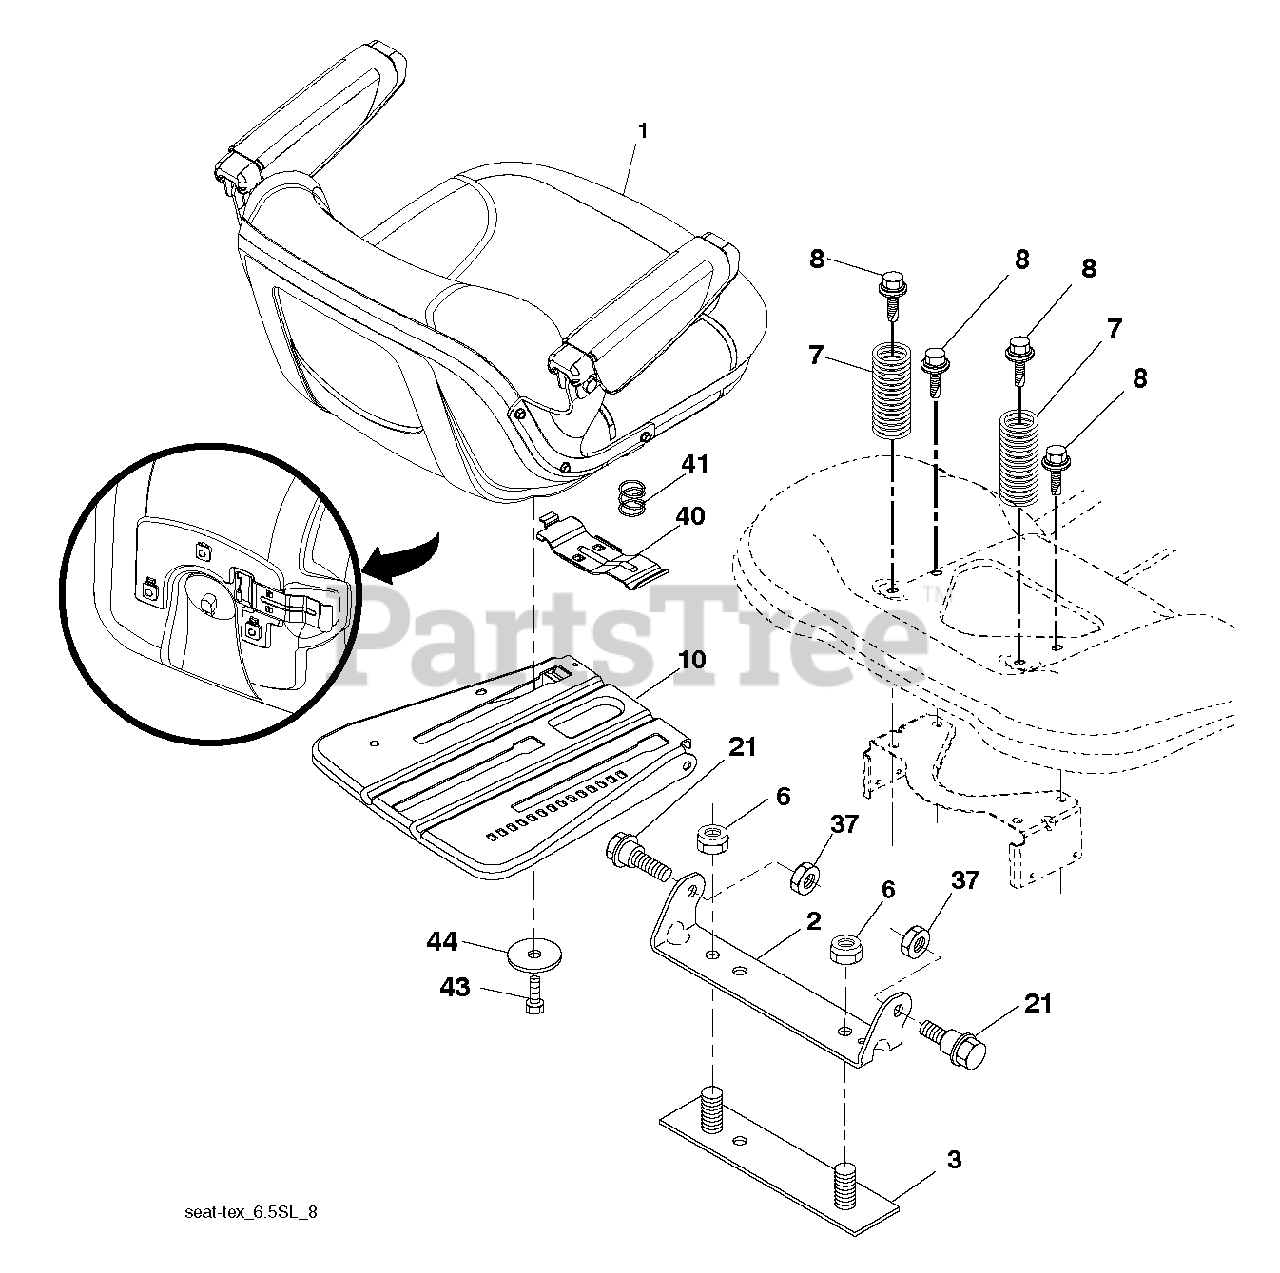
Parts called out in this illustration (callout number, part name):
1	SEAT.TH154.GREY.HUS.ARMREST
2	BRKT.PIVOT.FENDER
3	STRAP
6	NUT
7	SPRING.COMPRESSION.SEAT.BLACK
8	BOLT, 5/16-18 X 1 3/4
10	PAN.ASM.SEAT.3PT
21	BOLT.5/16-18X5/8.SHOULDER
37	NUT.71038.31-18.HEX.NYLOCK
40	HANDLE.SLIDE.SEAT.TEX.BLACK
41	SPRING.LATCH.SEAT.TEX
44	WASHER 13/32 X 2-3/8 X 12GA
